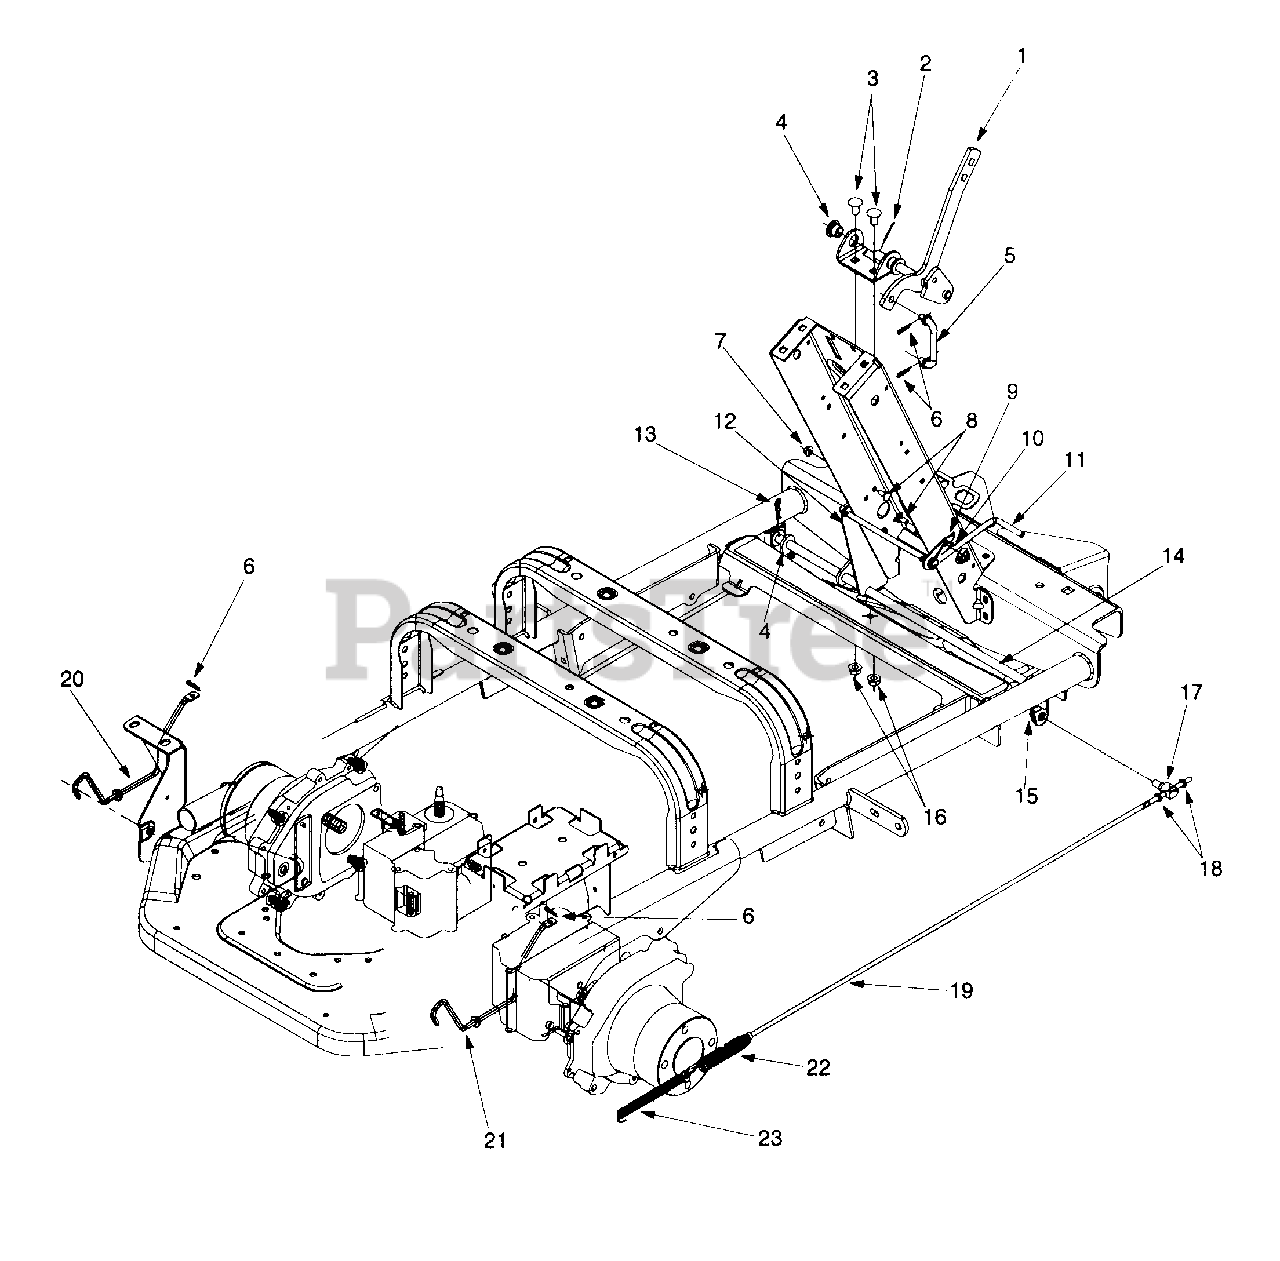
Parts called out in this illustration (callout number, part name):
1	Parking Brake Shift Ass'y
2	Cotter Pin
3	Carriage Bolt 3/8-16 x .75
4	Hex Flange Bearing .506 ID x .590
5	Connecting Brake Rod
6	Cotter Pin
7	Hex Flange Lock Nut 1/4-20
8	Carriage Screw 1/4-20 x .62
9	Retaining Rod Bracket
10	Torsion Spring 5/16
11	Parking Brake Retaining Rod
12	Support Plate
13	Cotter Pin
14	Brake Rod Ass'y
15	Flat Washer .385 ID x 1.0 OD
16	Flange Lock Nut 3/8-16
18	Jam Nut 1/4-28
19	Bracket Rod
20	Release Pump Rod LH
21	Release Pump Rod RH
22	Extension Spring
23	Extension Spring
